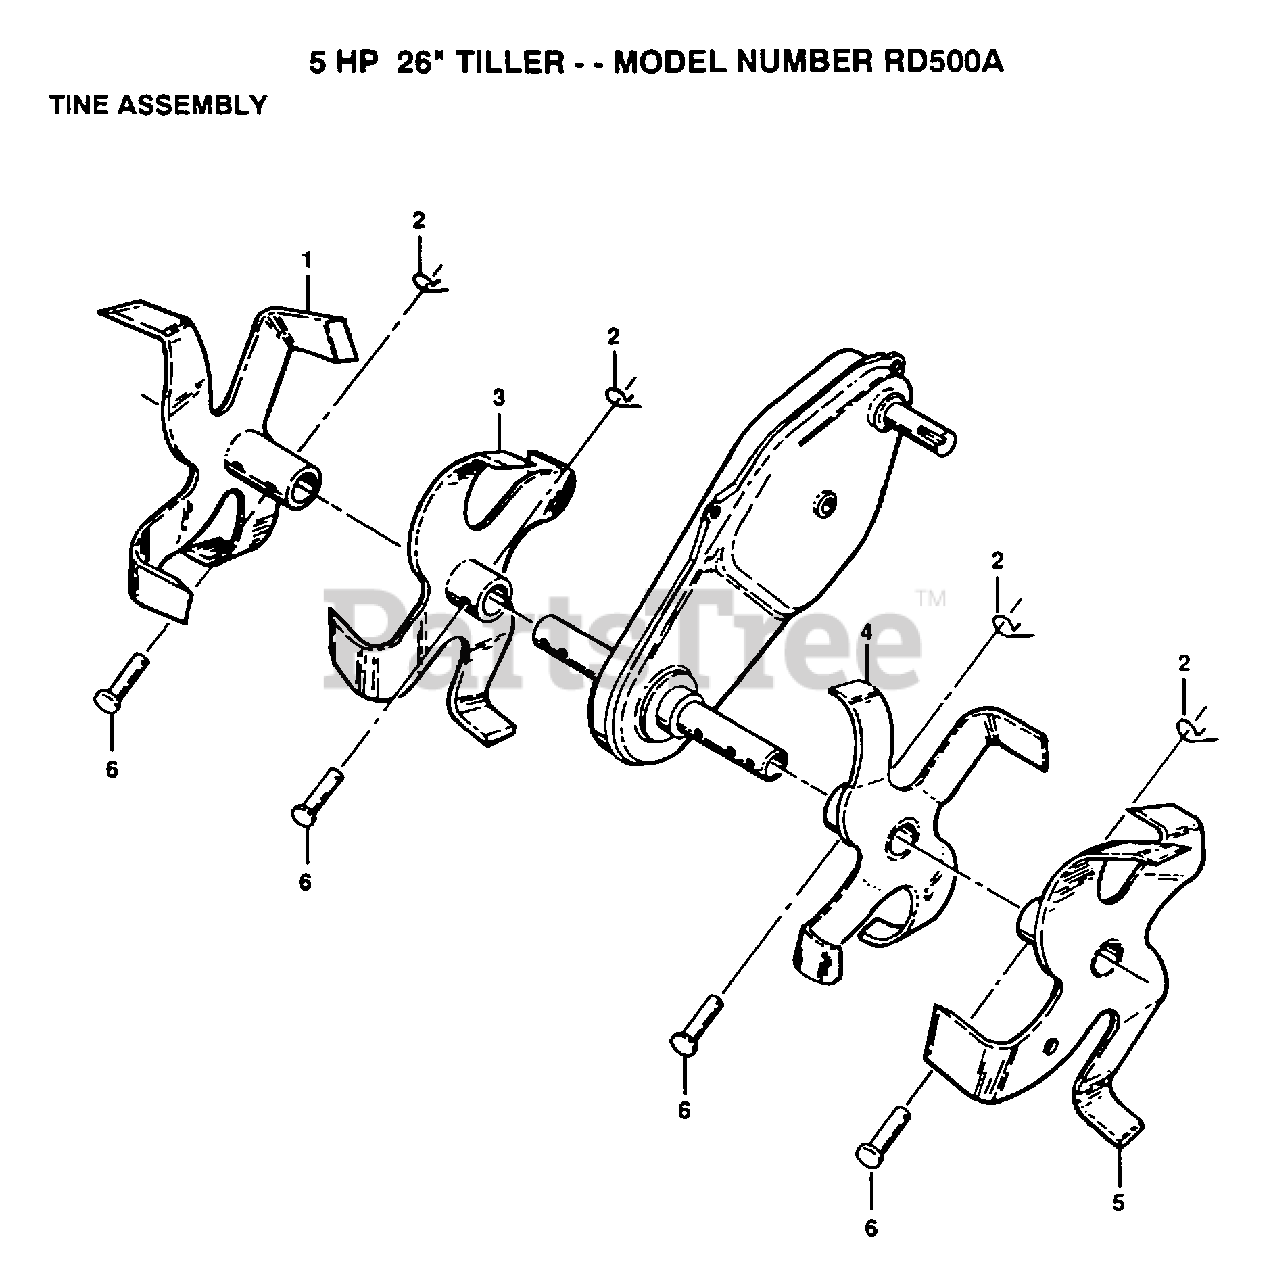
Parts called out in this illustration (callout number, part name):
1	TINE WELDMENT TI
2	RETAINER.SPRING
3	TINE TI
4	TINE TI
5	TINE WELDMENT TI
6	RIVET.PAN HD.1.75
